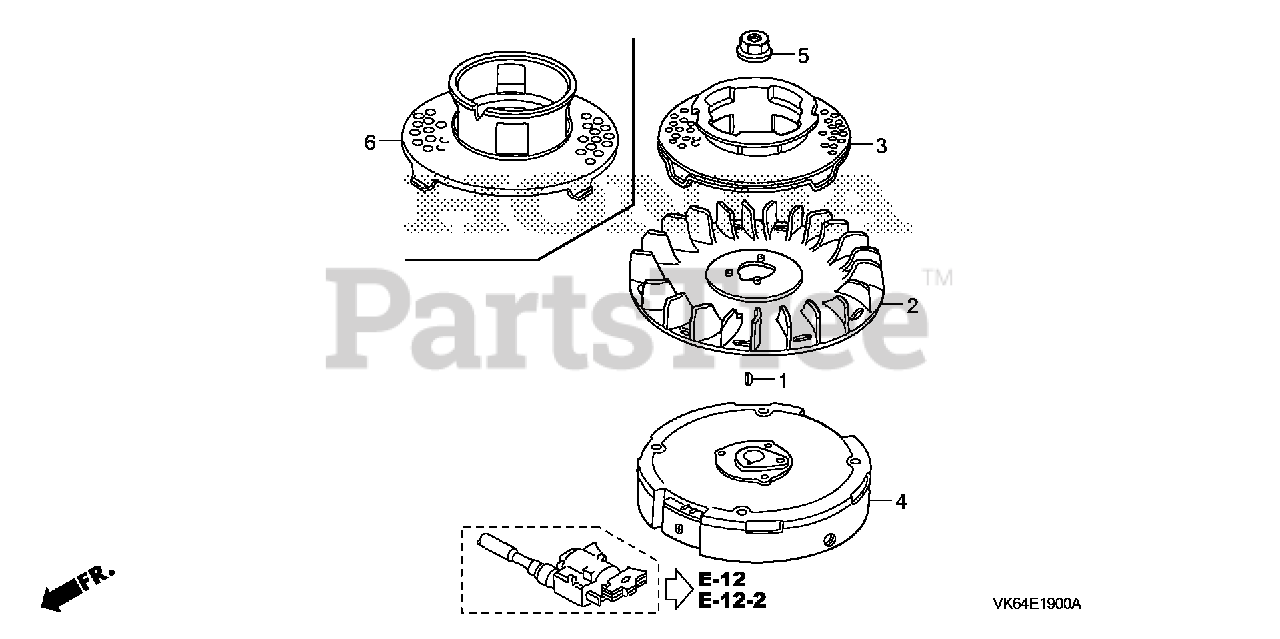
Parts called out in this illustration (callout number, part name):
1	KEY, SPECIAL WOODRUFF (25X18)
2	FAN, COOLING
3	PULLEY, STARTER
5	NUT, SPECIAL (14MM)
6	PULLEY, STARTER
